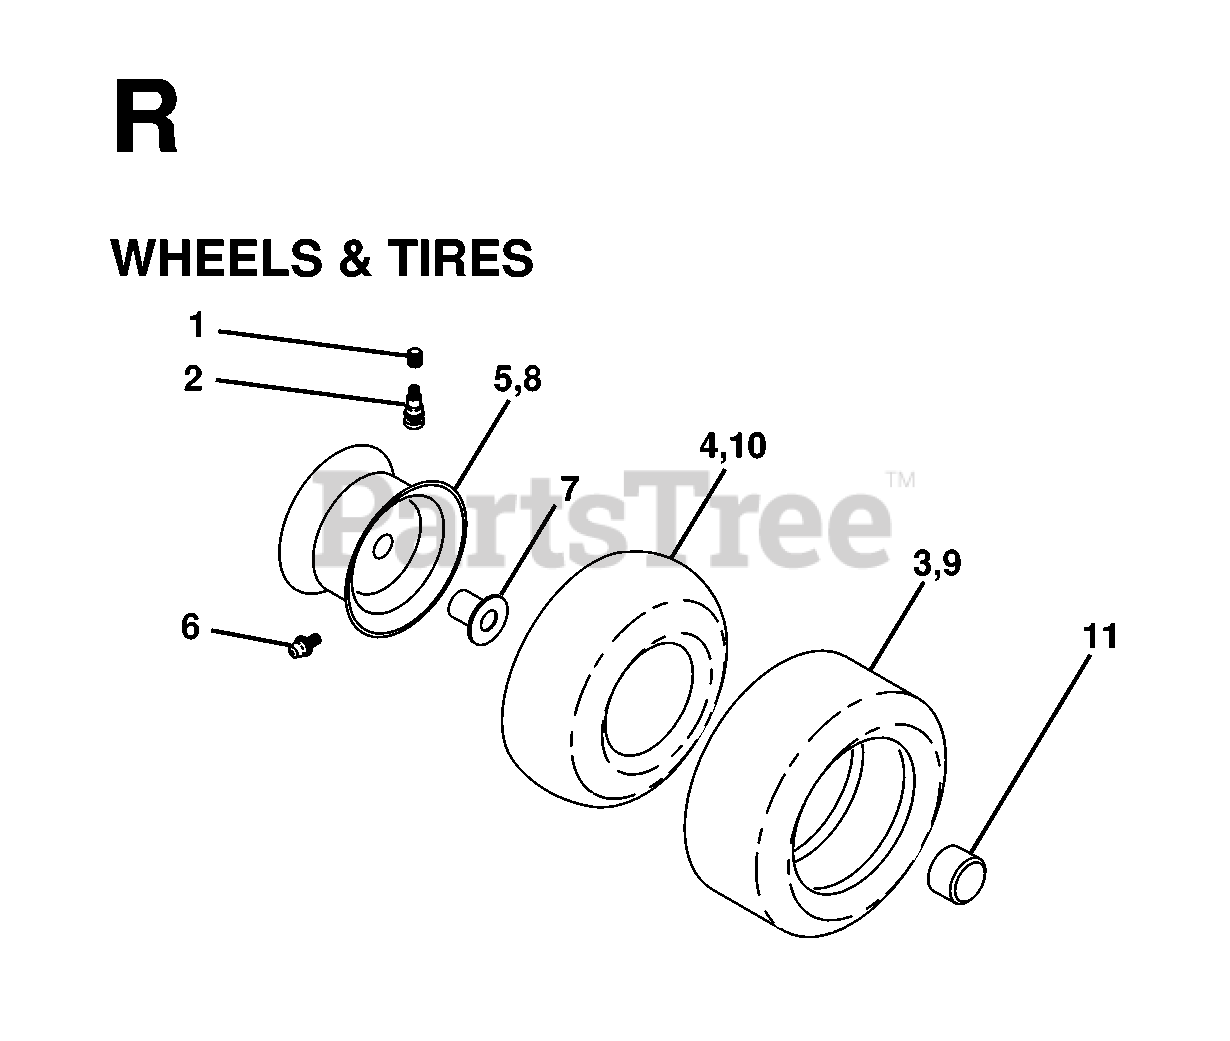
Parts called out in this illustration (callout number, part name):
1	VALVE CAP
2	VALVE STEM LT
3	TIRE HEAVY DUTY
4	TUBE.5.3/4.5/6
5	RIM ASM 6" FRONT SILVER
6	FITTING LT
7	BEARING T
8	RIM ASM 8" REAR SILVER
9	TIRE.TS.20X10-8
10	TUBE
11	CAP-HUB FRONT LT
